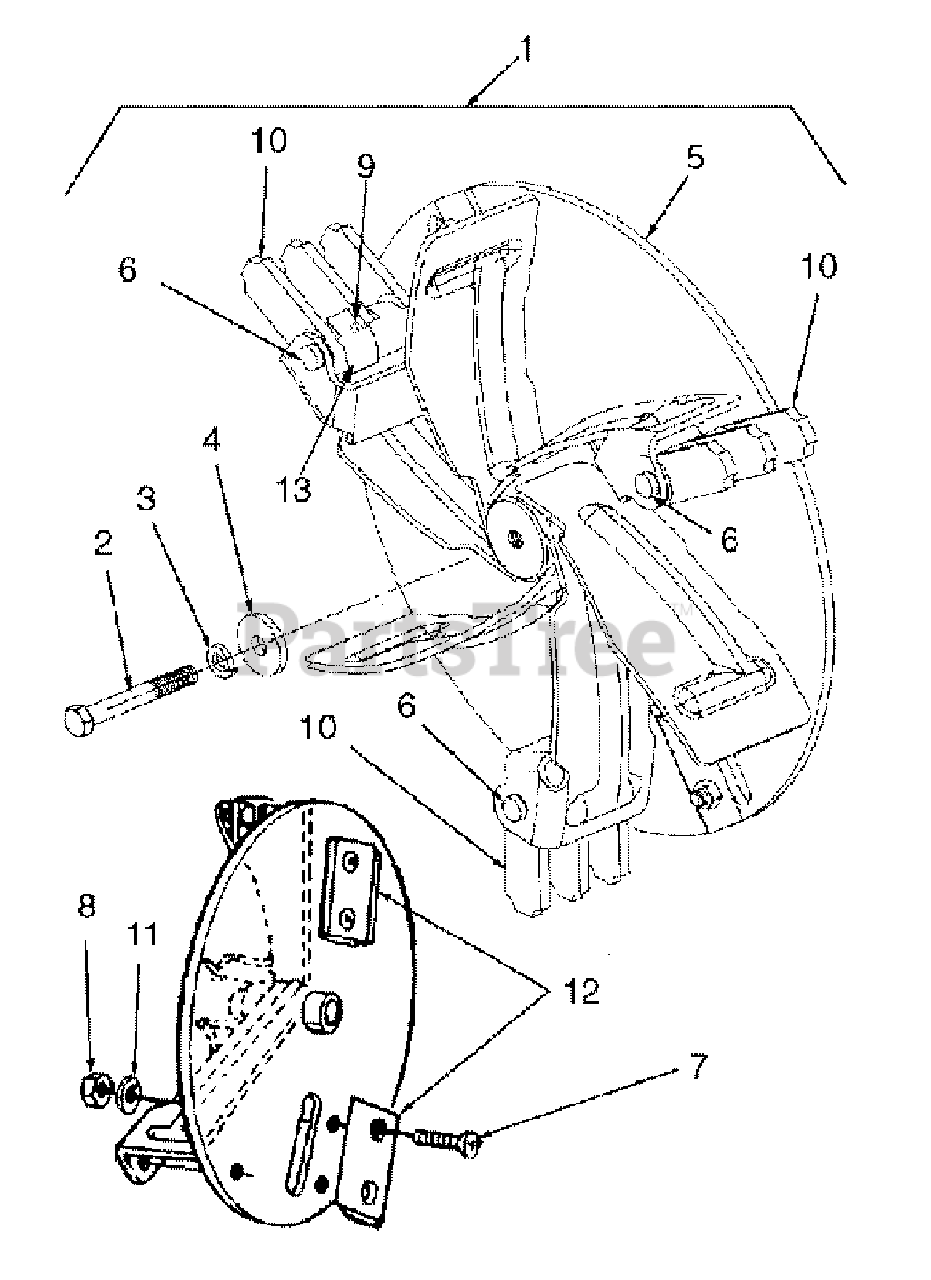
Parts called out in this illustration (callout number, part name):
1	Impeller Ass'y, Complete (For model 500)
1	Impeller Ass'y, Complete (For model 550)
2	Screw, Hex Cap, 3/8-24 x 2.75 GR5
3	Washer, Lock, 3/8 Heavy Duty
4	Washer, Flat, .406 x 1-1/4 HD
5	Impeller Assembly (For model 500)
5	Impeller Assembly (For model 550)
6	Pin, Clevis
7	Screw, Flat Hd. Cap, 5/16-24 x 1.0
8	Nut, Hex Insert Lock, 5/16-24
9	Pin, Spirol, .156 x 1.000 Std.
10	Blade, Flail
11	Washer, Lock, 5/16
12	Blade, Chipper
13	Clip, Retainer
